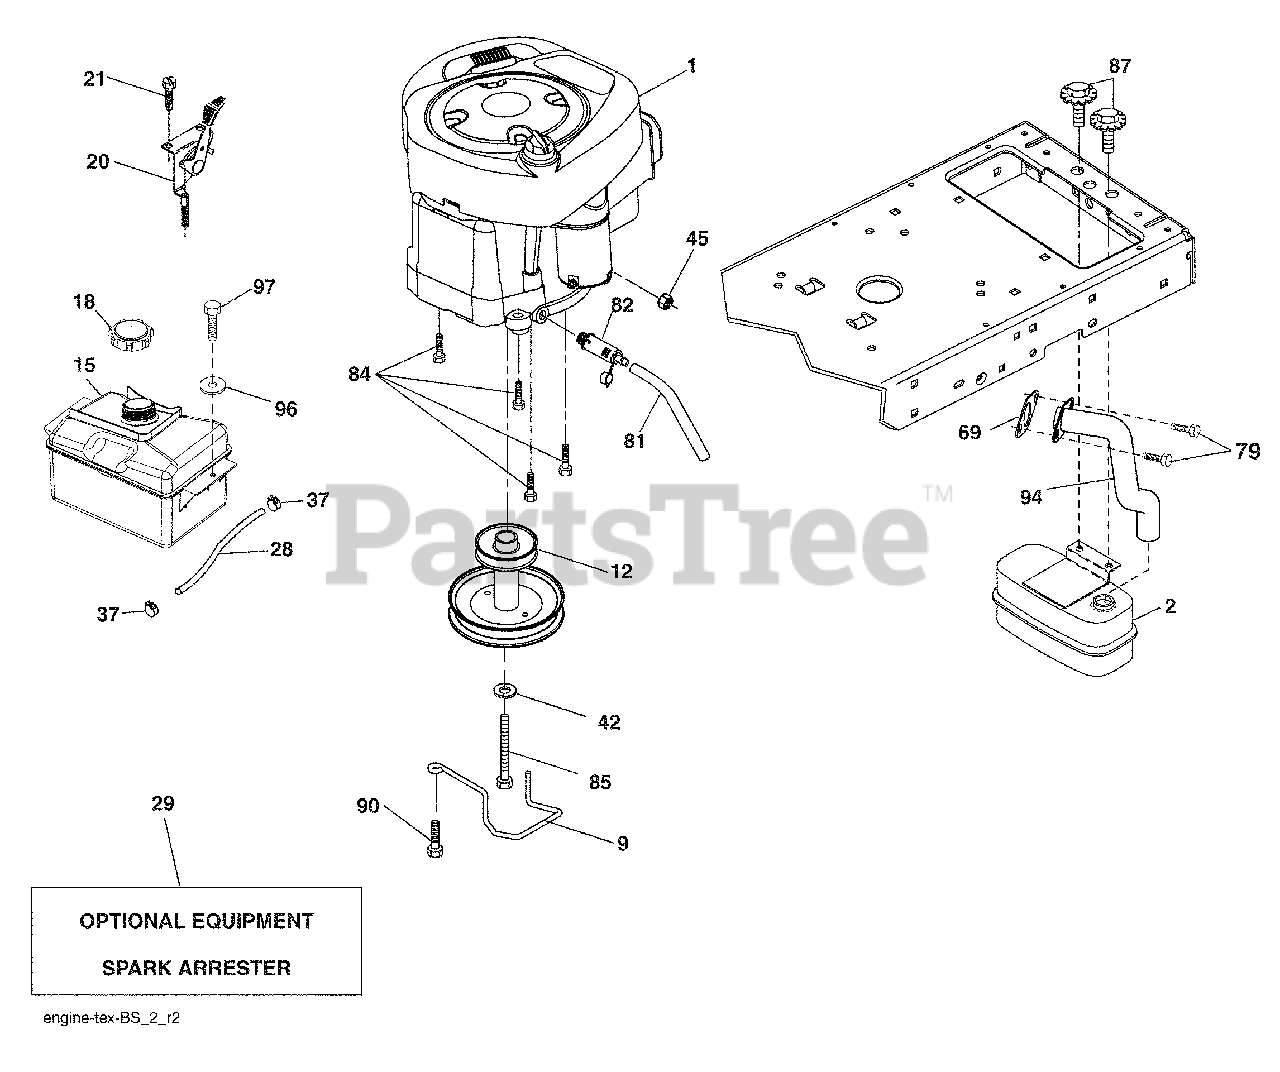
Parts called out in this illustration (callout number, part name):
9	Keeper Belt Engine
12	Pulley Engine
15	Tank Fuel
18	Cap Asm
20	Control Throttle
21	Screw #10 x 0.750 BOS Thread
28	Fuel Line
29	Spark Arrester Kit
37	Clamp Hose
42	Washer Lock 7/16
45	Nut Keps Hex 1/4-20 unc
69	Gasket
79	Screw 5/16-18 x 3/4
81	Tube Drain Oil Easy
82	Valve Drain Oil
84	Screw 3/8-16 x 1/4
85	Bolt Hex 7/16-20 x 4 Gr. 5
87	Bolt 5/16-18 unc x 3/4 w/sems
90	Screw 3/8-16 x 1
94	Exhaust Tube
96	Washer 9/32 x 7/8 x 16 Ga.
97	Screw 1/4-20 x 3/4
